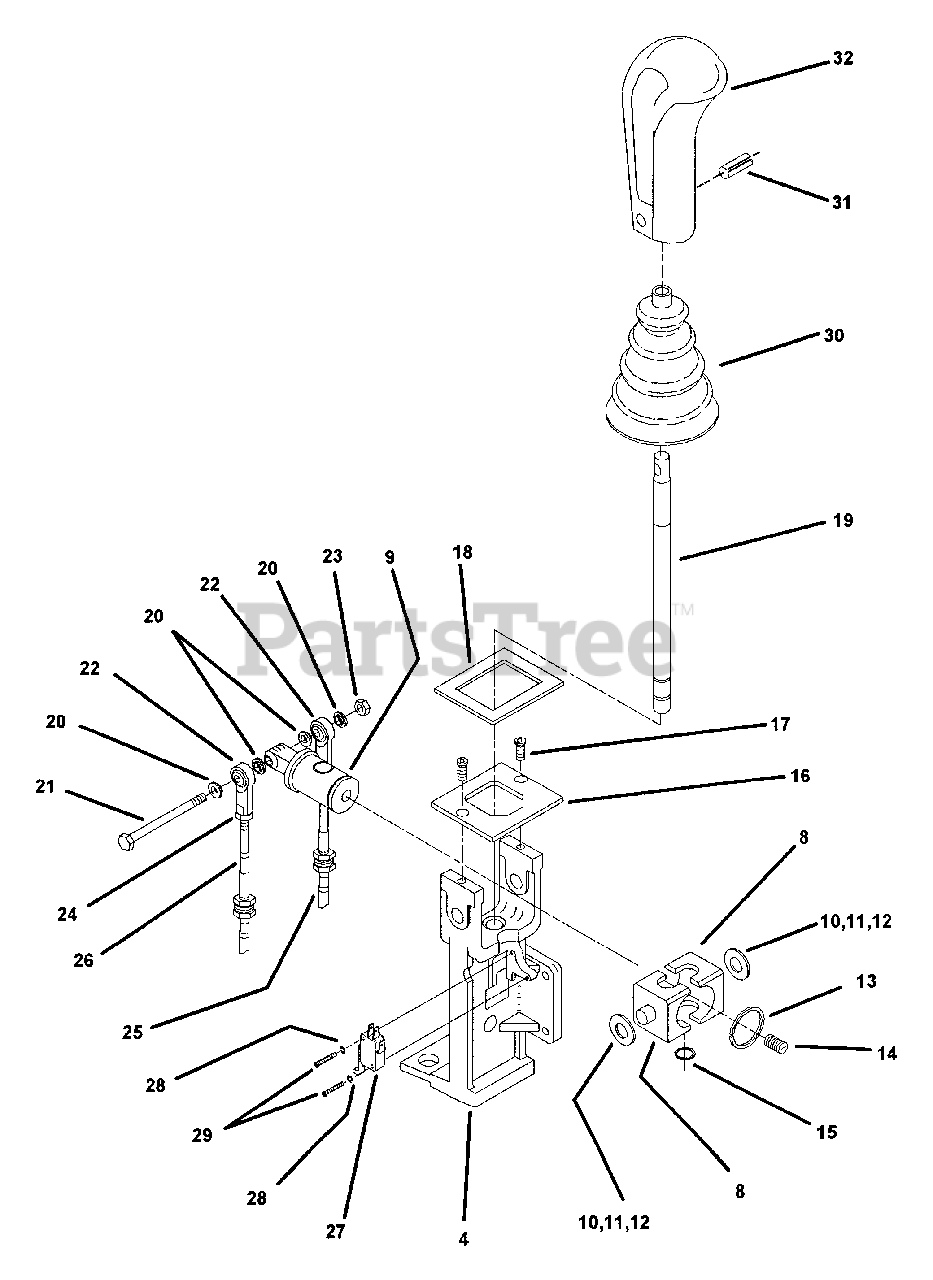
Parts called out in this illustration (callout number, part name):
4	JOYSTICK YOKE
8	PIVOT BLOCK, Delrin Plastic
9	PIVOT SHAFT, Delrin Plastic
10	SHIM WASHER, 1/2 ID x 1 OD x .005 Thick
11	SHIM WASHER, 1/2 ID x 1 OD x .010 Thick
12	SHIM WASHER, 1/2 ID x 1 OD x .020 Thick
13	SNAP RING, Spirlock
14	BALL PLUNGER, 3/8-16 X 5/8"
15	SNAP RING, 1/2"
16	TOP PLATE, Joystick
17	SCREW, 1/4-20 X 1/2", Flathead
18	GASKET, Foam
19	JOYSTICK SHAFT
20	BUSHING, Ball Joint
21	CAP SCREW, 1/4-20 X 3", Hex Head
22	BALL JOINT, 1/4-28, Female
23	NUT, 1/4-20, Nylock
24	NUT, 1/4-28, (comes with 26 & 27)
25	CABLE, PUSH-PULL, 55"
26	CABLE, PUSH-PULL, 25-1/2"
27	SWITCH, SPDT, Miniature
28	LOCK WASHER, #4 Star
29	SCREW, #4-40 X 3/4"
30	BELLOWS BOOT
31	ROLL PIN, 3/16 X 1"
32	HANDLE GRIP
